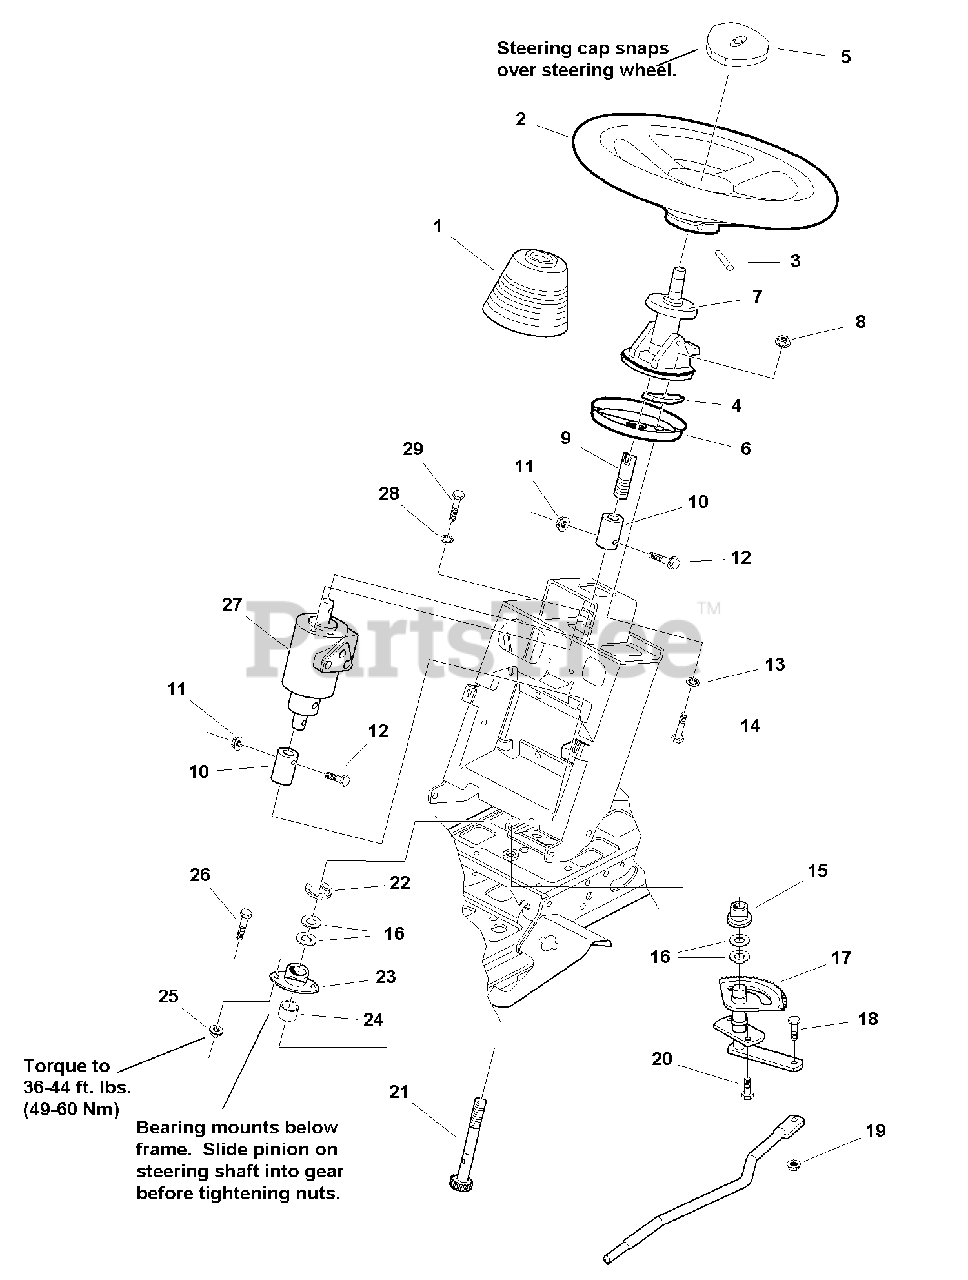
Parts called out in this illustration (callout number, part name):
1	BOOT, Tilt Steering Unit
2	STEERING WHEEL, Straight Shaft
3	ROLL PIN
5	CAP, Steering Wheel, Plain
6	MOUNTING PLATE
7	TILT STEERING UNIT
8	TILT STEERING UNIT
8	NUT, Hex KEPS, 1/4-20
9	ADAPTER, 2-13/16 Long
10	COUPLER, 2-3/8 Long
11	NUT, Hex Lock ESNA Light, 5/16-18
12	CAPSCREW, Hex Head 5/16-18 x 1-3/4
13	NUT, Push
14	CARRIAGE BOLT, 1/4-20 x 1-1/4
15	BUSHING, Nylon
16	WASHER, 3/4
17	GEAR &, Shaft ASSEMBLY, Steering
18	CAPSCREW, Hex Head, 3/8-16 x 1-1/4
19	NUT, Hex Flange Two-Way Lock, 3/8-16
20	CAPSCREW, Hex Washer Head Taptite, 5/16-18 x 3/4
21	SHAFT & PINION ASSEMBLY, Steering Power wtih Tilt
22	RING, Clipring Extension
23	BEARING, 3/4 x 1-11/16
24	SPACER, 3/8" Long
25	NUT, Hex Flange Whiz Lock, 3/8-16, Small
26	CARRIAGE BOLT, 3/8-16 x 3/4
27	GENERATOR, Torque, Power Steering Unit
28	LOCKWASHER, Spring, 5/16
29	CAPSCREW, Hex Head, 5/16-18 x 3/4
